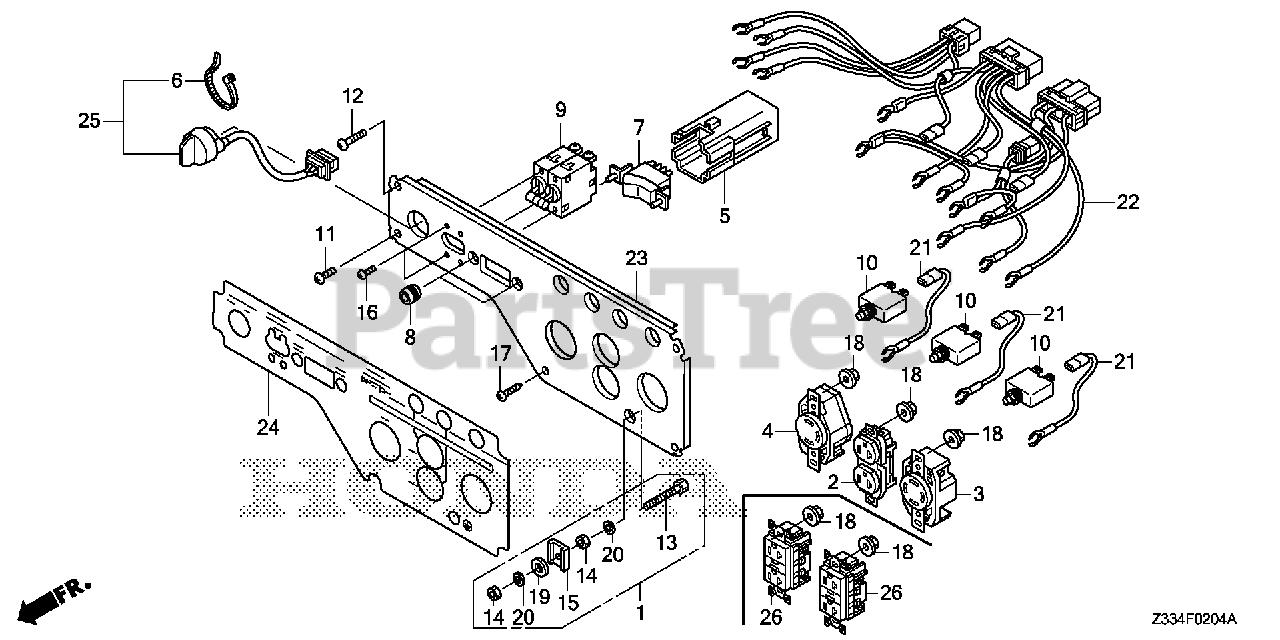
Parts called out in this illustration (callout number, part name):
1	TERMINAL SET, GROUND
3	RECEPTACLE (20A-125/250V)
4	RECEPTACLE (30A-125V)
5	CONNECTOR (12P)
6	BAND
7	SWITCH ASSY., VOLT CHANGE
8	MOUNT, VOLT CHANGE SWITCH
9	BREAKER, CIRCUIT (17A)
10	PROTECTOR, CIRCUIT (20A)
11	SCREW, TRUSS (6X18)
12	SCREW, TRUSS (6X30)
13	BOLT, HEX. (6X28)
14	NUT, HEX. (6MM)
15	RETAINER (6MM)
16	SCREW, PAN (3X5)
17	SCREW, TAPPING (5X12) (PO)
18	NUT, FLANGE (4MM)
19	WASHER, PLAIN (6MM)
20	WASHER, SPRING (6MM)
21	SUB-WIRE ASSY.
22	WIRE HARNESS ASSY., CONTROL
23	PANEL, CONTROL *NH105* (MAT BLACK)
24	MARK, PANEL
25	SWITCH ASSY., ENGINE STOP
26	RECEPTACLE (20A-125V) (GFCI)
